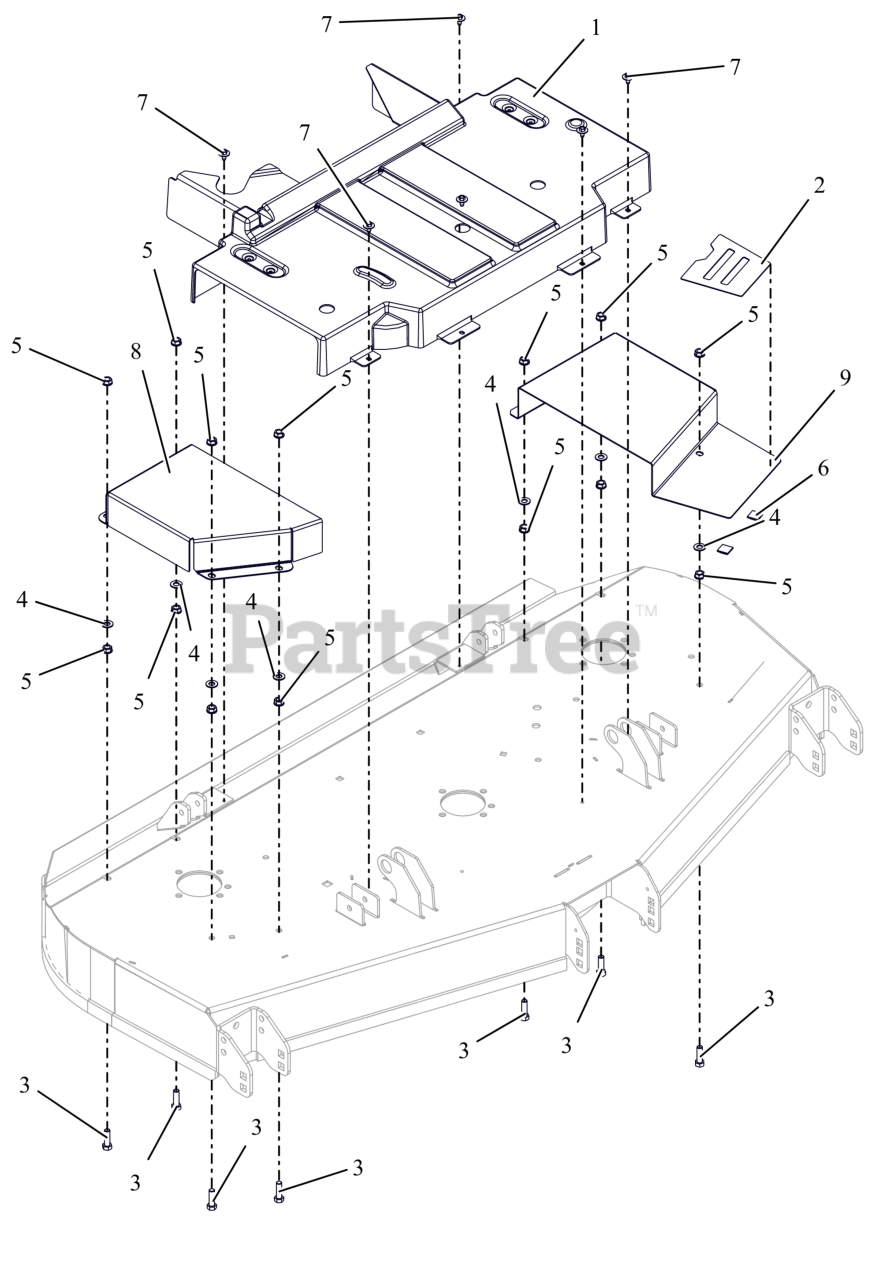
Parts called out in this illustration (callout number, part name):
1	GUARD, CENTER DECK SPINDLE CE
2	GRIP TAPE 52-60 BELT COVER
3	BLT, HEX .38-16X1.25 G5 ZCC
4	WSHR,FLT .406X.812X.065 ZCC
5	NUT, SPNLK-FLG .38-16 G5 ZCC
7	SCR, TAP .25-20X.50 LG HWH ZCC
8	GUARD,BELT 52" RIGHT CE
9	GUARD, BELT 60" LEFT CE (ORANGE)
